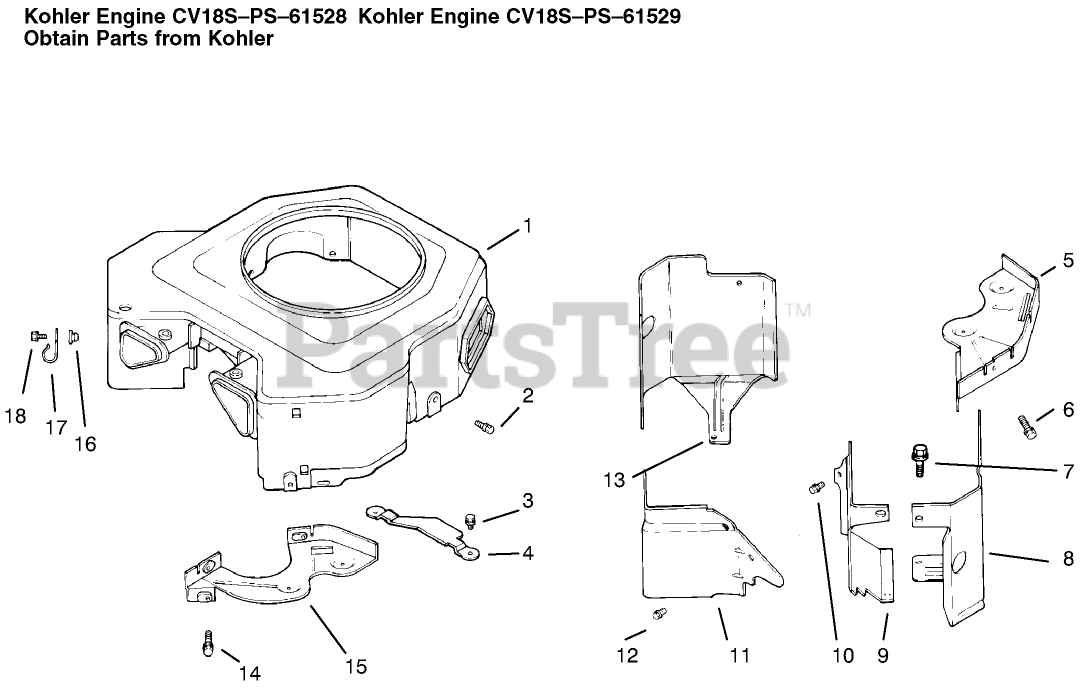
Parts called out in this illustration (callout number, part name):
1	Housing-Blower ASM (Only C)n: 72103, 72083)
4	Guard-Flywheel (Only On: 72103, 72083)
5	Plate-Backing #2 side
8	Baffle Cylinder #2 Side
9	Baffle-Valley #1 Side
11	Baffle-Valley #2 Side (Only On: 72103, 72083)
13	Baffle-Cyl. #1 Side
15	Plate-Backing #1
17	Clip-Cable (Only On: 72103)
